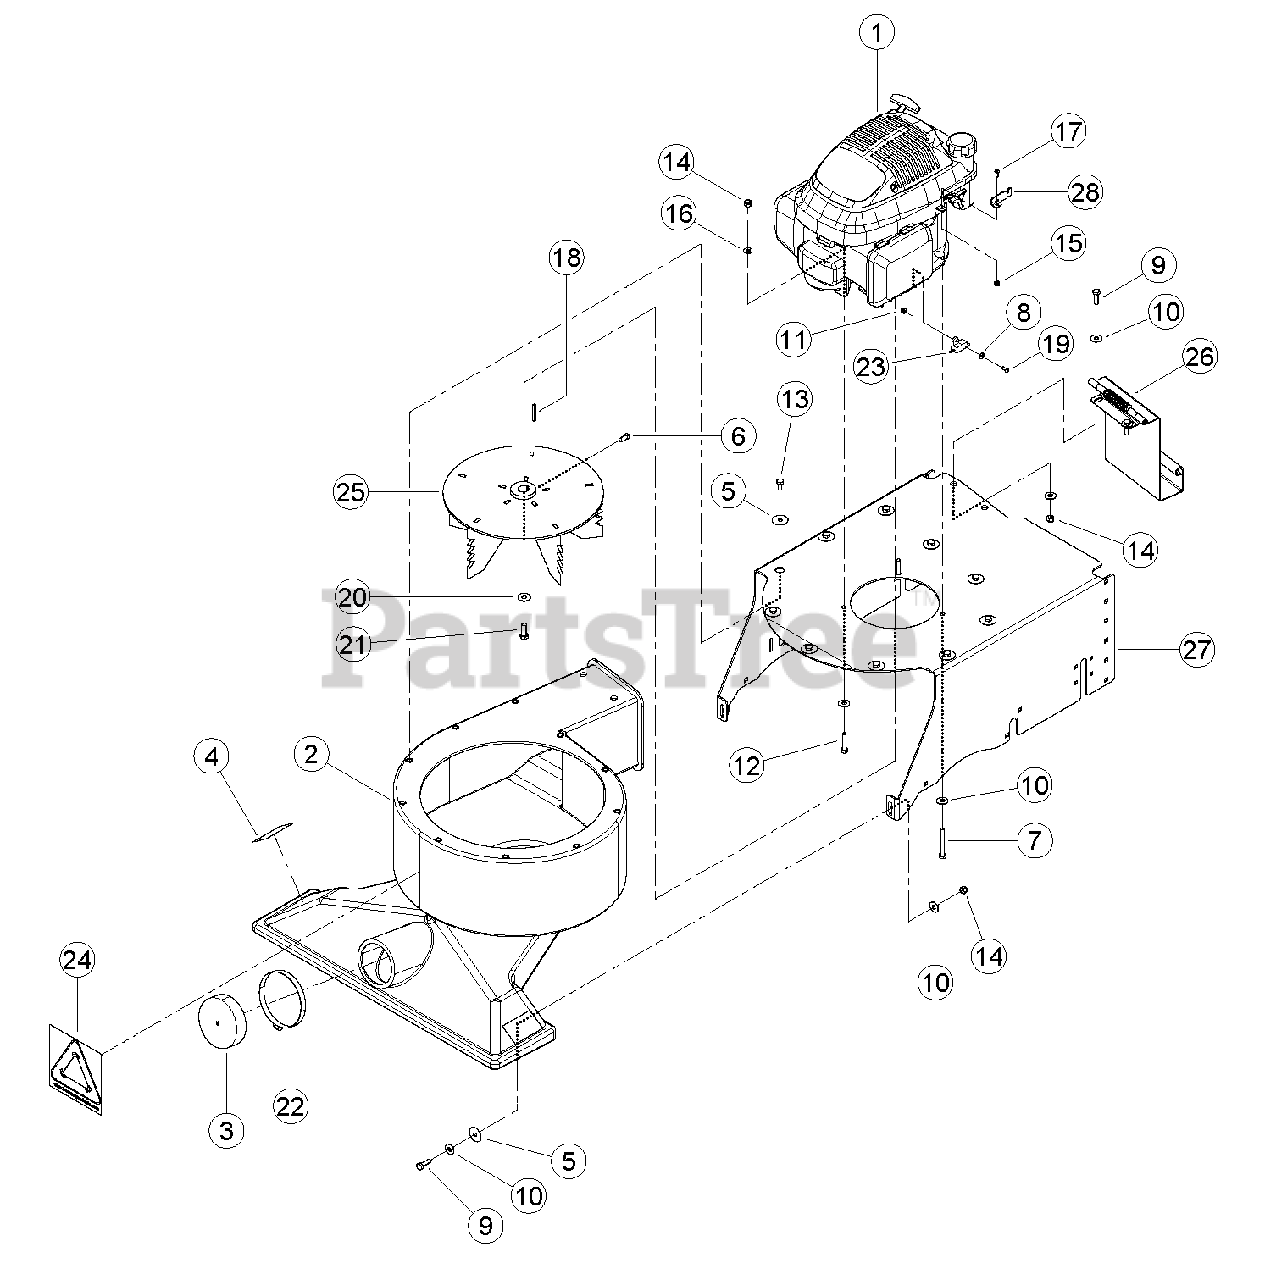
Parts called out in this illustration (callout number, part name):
1	ENGINE, 5.5 HP HONDA GCV (WV160 ONLY) (FOR SERVICE SEE ENGINE OWNER'S MANUAL OR NEAREST HONDA INDUSTRIAL ENGINE DEALER)
2	HOUSING, FAN W/INTAKE
3	CAP, ROUND VINYL
4	DECAL, DANGER
5	WASHER, 5/16 FENDER ZP
6	SCREW, 5/16-18 X 5/8 SQ HD SET
7	BOLT, 5/16-18 X 1-3/4 HCS GR5 ZP (WV160 ONLY)
8	WASHER, #8 SAE FLAT (WV160 ONLY)
9	BOLT, 5/16 X 1 HHCS GR5 ZP
10	WASHER, 5/16 FLAT ZP
11	NUT, #8 X 32 NYLOCK (WV160 ONLY)
12	BOLT, 5/16 X 1-1/2 HEX HD GR5 ZP (WV190 ONLY)
13	BOLT, 5/16 X 5/8 HEX HD GR5 ZP
14	NUT, 5/16 NE NYLOCK ZP
15	NUT, 10/24 NYLOCK TYPE NM, ZP (WV160 ONLY)
16	WASHER, 5/16 SAE FLAT ZP
17	SCREW, MCH 10-24 X 1/2 PAN HD PH ZP (WV160 ONLY)
18	KEY, 3/16 SQUARE X 1-1/4 LONG PLAIN
19	SCREW, #8 X 32 X 3/4 PAN PHP ZP (WV160 ONLY)
20	WASHER, 3/8 GR8 USS ZP
21	BOLT, 3/8 X 1 HHCS GR5 NF ZP
22	CLAMP, 4 IN. HOSE
23	SWITCH, HONDA ENGINE KILL (WV160 ONLY)
24	DECAL, COLLECT IT
25	WELDMENT, BEARVAC ROTOR (REPLACED AND SUPERSEDED PN 73612-00.)
26	ASSEMBLY, EXHAUST DOOR
27	SUPPORT, BEARVAC FRAME
28	PLATE, HONDA BRACKET HOLDER (WV160 ONLY)
